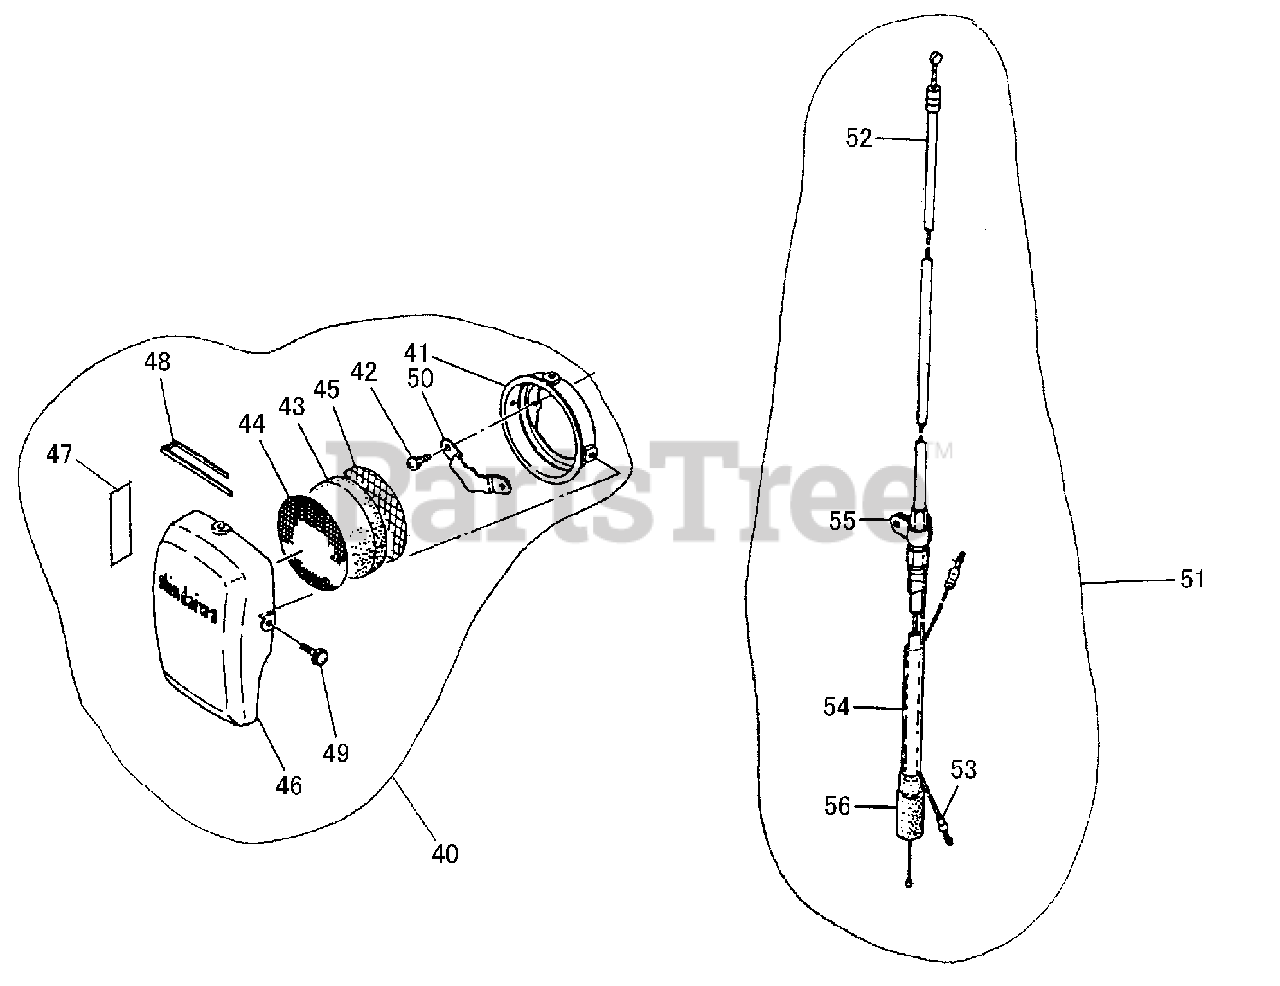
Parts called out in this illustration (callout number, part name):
40	FILTER ASSY, AIR
41	CASE, AIR FILTER
42	SCREW
43	FILTER, AIR
44	SCREEN - FRONT
45	SCREEN, REAR
46	COVER, AIR FILTER
47	LABEL, CHOKE
48	CLIP, FILTER RETAINING
49	SCREW 4
51	CABLE ASSY, THROTTLE
52	CABLE, THROTTLE
53	LEAD
54	PIPE
55	CLAMP
56	CAP, CARBURETOR
